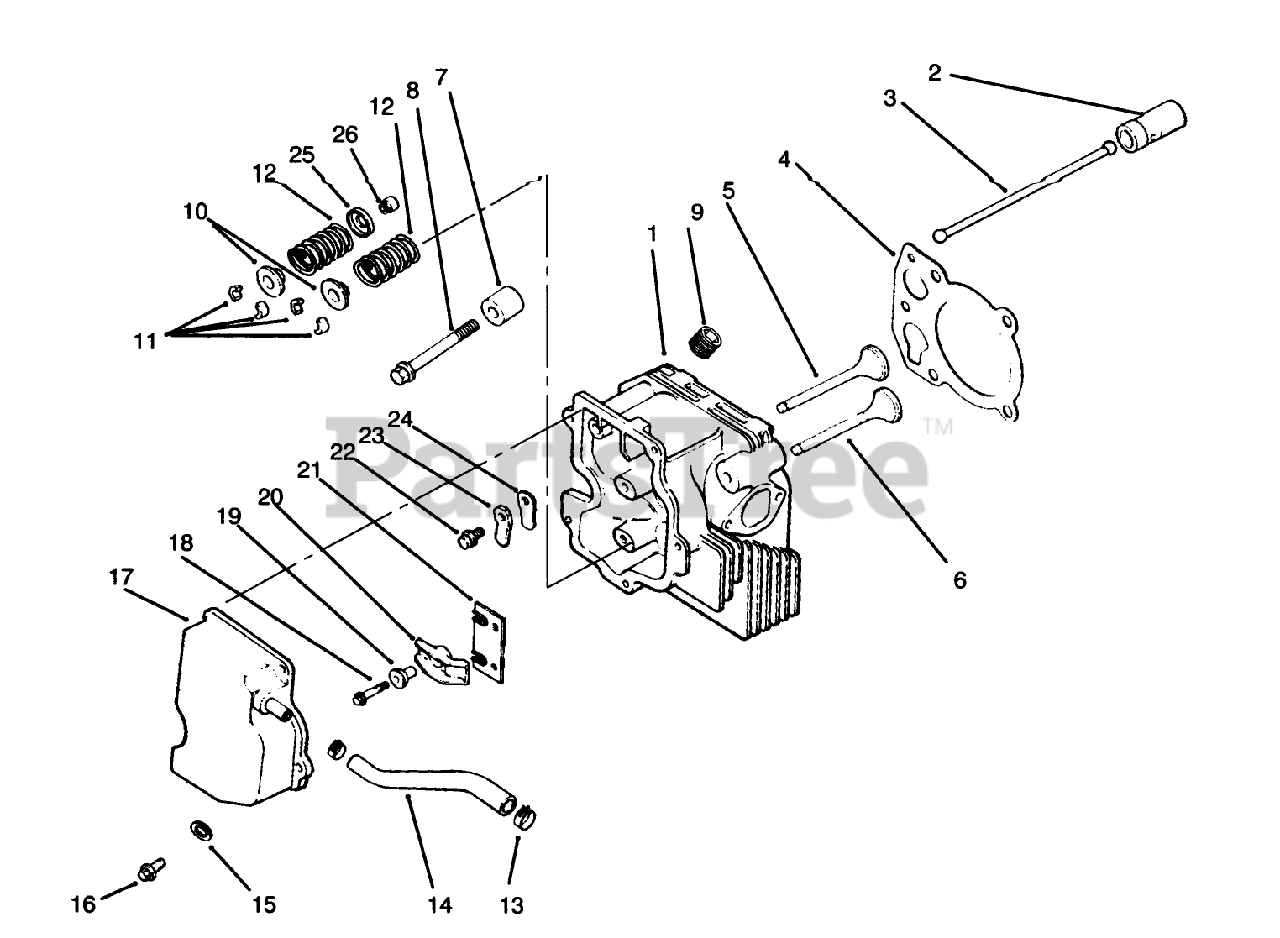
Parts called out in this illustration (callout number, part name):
1	Cylinder Head
2	Lifter-Valve
3	Rod-Push (Only On: 72042,72043,72062,72063)
4	Gasket-Cylinder Head (Only On: 72042, 72063, 72062, 72043)
5	Valve-Intake STD (Only On: 72042, 72063, 72062, 72043)
5	Valve-Intake .25 (Only On: 72042,72043,72062,72063)
6	Valve-Exhaust STD (Only On: 72042,72043,72062,72063)
6	Valve-Exhaust .25 (Only On: 72042, 72063, 72062, 72043)
7	Spacer-Head Bolt Exhaust (Only On: 72042, 72063, 72062, 72043)
8	Screw M10x1.5x80 (Only On: 72042, 72063, 72062, 72043)
10	Cap-Valve Spring
11	Kit-Retainer
12	Spring-Valve Intake (Only On: 72042, 72063, 72062, 72043)
13	Clamp
14	Hose-Breather (Only On: 72042, 72063, 72062, 72043)
15	Washer-Flat (Only On: 72042, 72063, 72062, 72043)
17	Cover-Valve W/Nipple (Only On: 72042, 72063, 72062, 72043)
19	Ball-Rocker Pivot
20	Arm-Rocker
21	Plate-Guide (Only On: 72042, 72063, 72062, 72043)
23	Retainer-Reed
24	Reed-Breather
25	Retainer-Spring
26	Seal-Valve Stem
